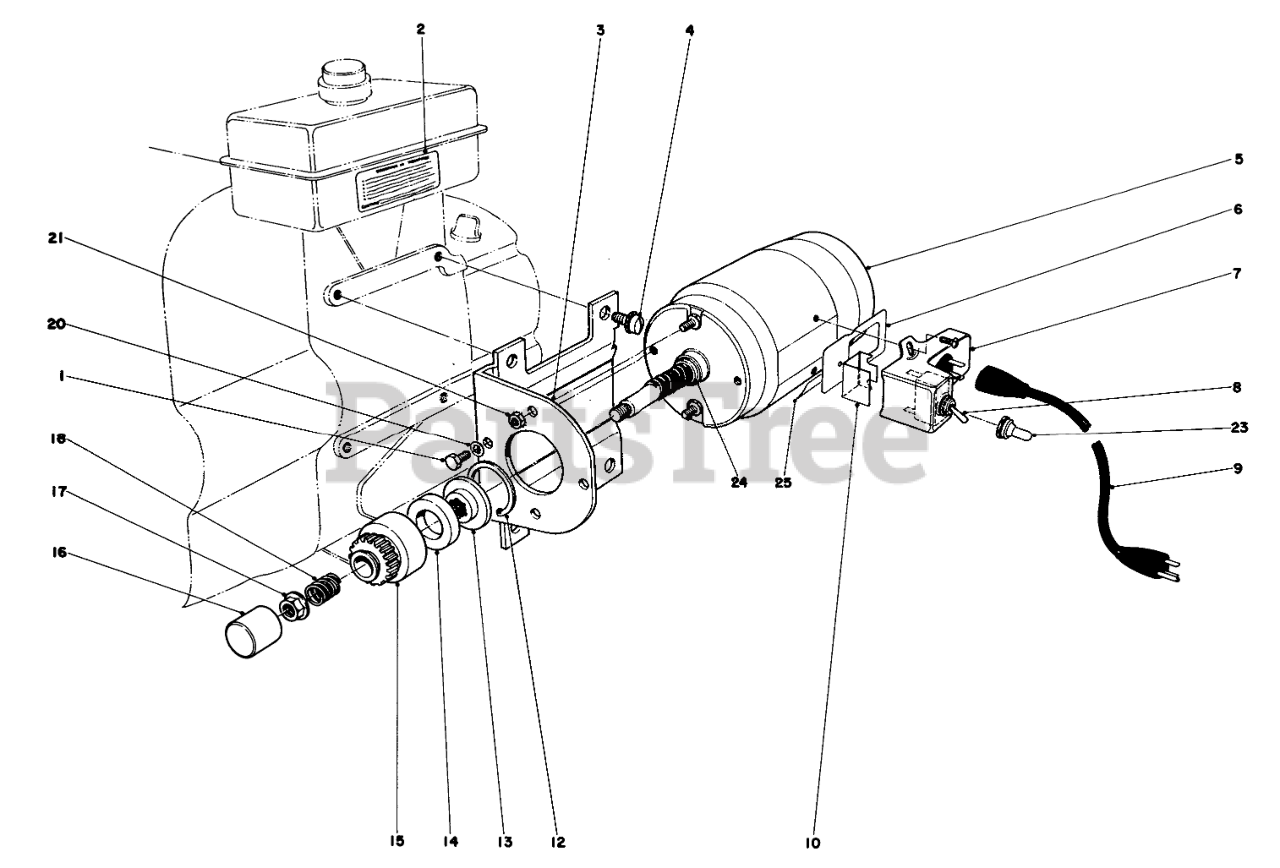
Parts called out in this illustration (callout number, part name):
1	SLOT HD SCREW
2	Instruction Decal
3	BRACKET
4	1/4-20X1/2 HX HD SEMS
5	Starter Motor
6	GASKET
7	Switch & Plug Housing
8	Switch (Incl. Ref. #23)
10	SWITCH INSULATOR
12	Retaining Clip
13	Pinion Nut
14	Rubber Ring
15	PINION 16 TOOTH
16	WEATHER CAP
17	NUT-HHF
18	COMPRESSION SPRING
20	WASHER-LOCK, INT
21	NUT-KEPS
23	BOOT-SWITCH
24	Spacer
25	Decal
